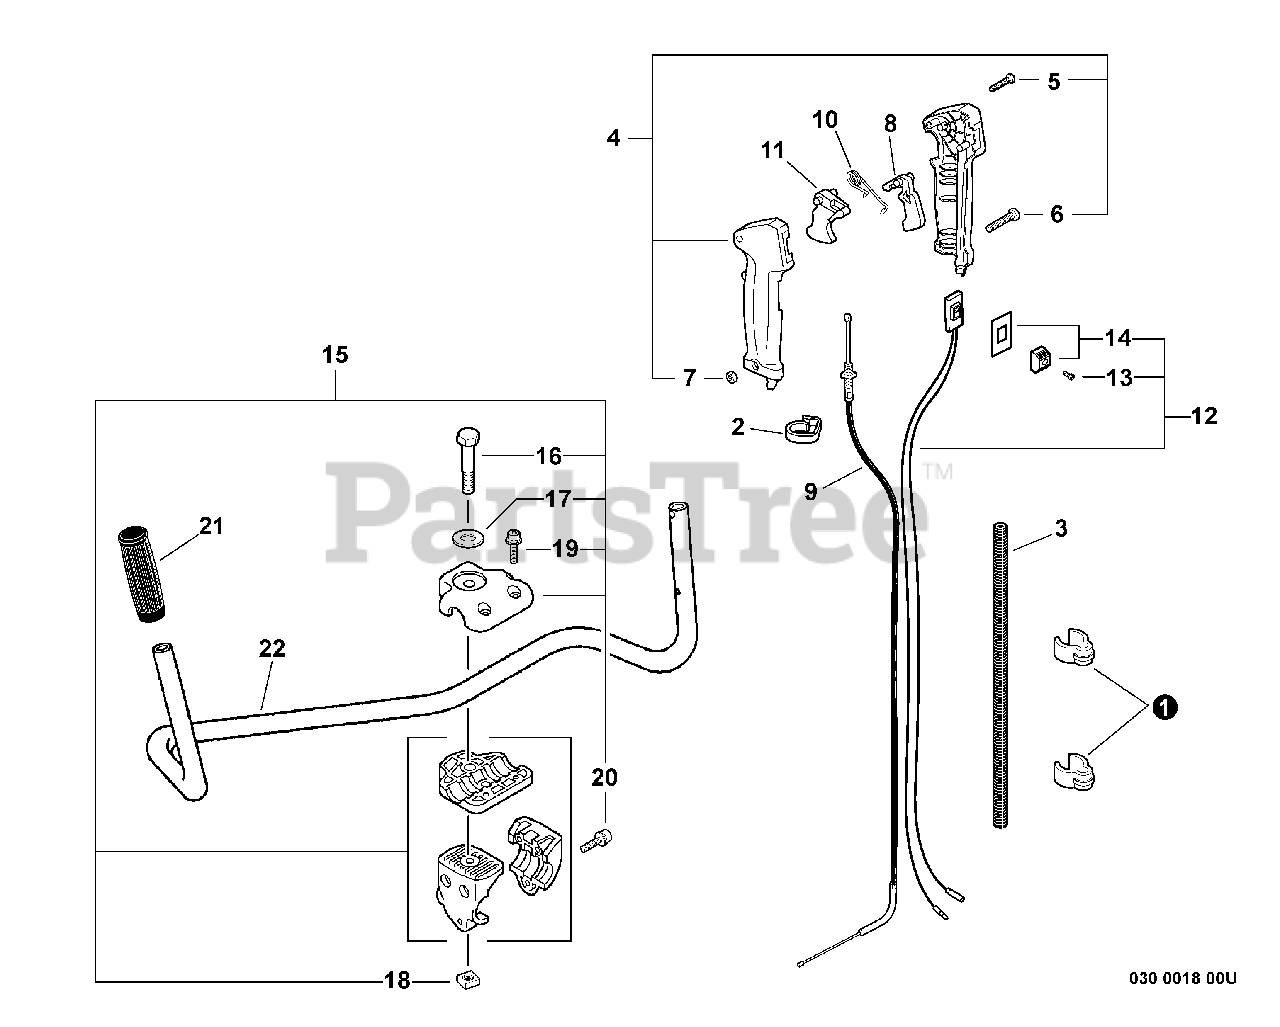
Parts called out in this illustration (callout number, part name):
3	TUBE, FLEXIBLE 7×790
4	CONTROL HANDLE KIT
5	SCREW 3×25
6	SCREW 5×30
7	NUT M5
8	LOCKOUT, THROTTLE
9	CABLE, THROTTLE
10	SPRING, TORSION
11	TRIGGER, THROTTLE
12	SWITCH, ON-OFF
13	SCREW 3×10
14	KNOB, SWITCH - ORANGE
15	BRACKET KIT, HANDLEBAR
16	BOLT 8×55
17	WASHER 8
18	NUT 8×1.25
19	BOLT 5×20
20	BOLT 5×30
21	GRIP, HANDLE
22	HANDLEBAR
